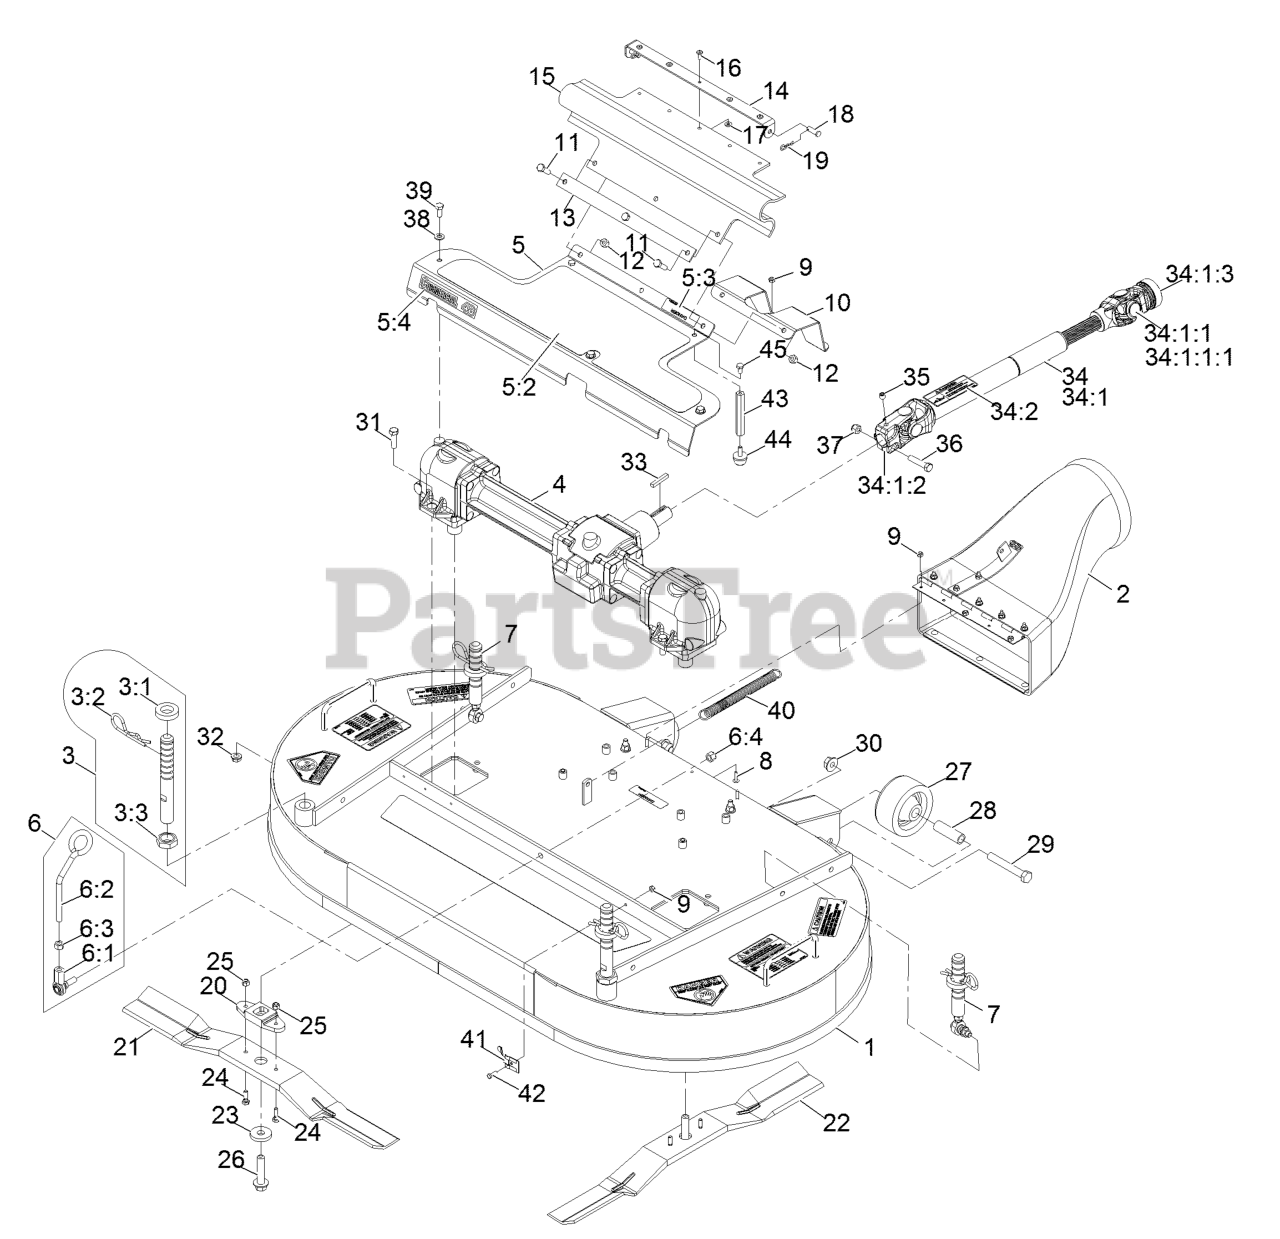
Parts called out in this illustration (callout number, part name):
1	DECK DECAL AND BAFFLE ASM
2	DISCHARGE TUBE ASM
3	FRONT DECK HEIGHT ADJUST
3:1	SPACER-DECK SUPPORT
3:2	PIN-CUT HEIGHT
3:3	NUT-JAM
4	GEAR BOX ASM
5	ASM,GEARBOX COVER 48 W/DE
5:2	PAD-ANTI SKID
5:3	DECAL-COVER, MISSING
5:4	DECAL,COMMERCIAL 48
6	DECK LATCH ASM
6:1	BALLJOINT-RH
6:2	LATCH-DECK
6:3	NUT-HEX
6:4	NUT-LOCK
7	REAR DECK HEIGHT ADJUST A
8	SCREW-HEAD, TRUSS
9	NUT-LOCK, NI
10	GUARD-DRIVE SHAFT
11	SCREW-HH
12	NUT-LOCK, NI
13	STRAP-DRIVE, LINE COVER
14	BRACKET-GUARD, PTO
15	GUARD-PTO
16	RIVET-BLIND
17	WASHER-FLAT
18	PIN-CLEVIS
19	PIN-COTTER
20	DRIVER-BLADE
21	BLADE,25 INCH RH
22	BLADE,25 INCH LH
24	BOLT-SHEAR
25	NUT-LOCK, NI
26	BOLT-BLADE
27	ROLLER-DECK
28	SPACER-ROLLER
29	SCREW-HH
30	NUT-HHF
31	SCREW-HH
32	NUT-HHF, WHIZ
33	KEY-SQUARE
34	DRIVE SHAFT ASM
34:1	Shaft,Drive Telescoping
34:1:1	U-JOINT KIT
34:1:1:1	FITTING-GREASE
34:1:2	YOKE-KEYED
34:1:3	YOKE-QUICK DISCONNECT
34:2	DECAL-DRIVELINE
35	SCREW-SET, HSH
36	SCREW-HH
37	NUT-LOCK, NI
38	WASHER-PLAIN
39	SCREW-HH
40	SPRING-EXTENSION
41	CLIP-DECK, HOLD UP ROD
43	STAND-OFF
45	SCREW-HH
